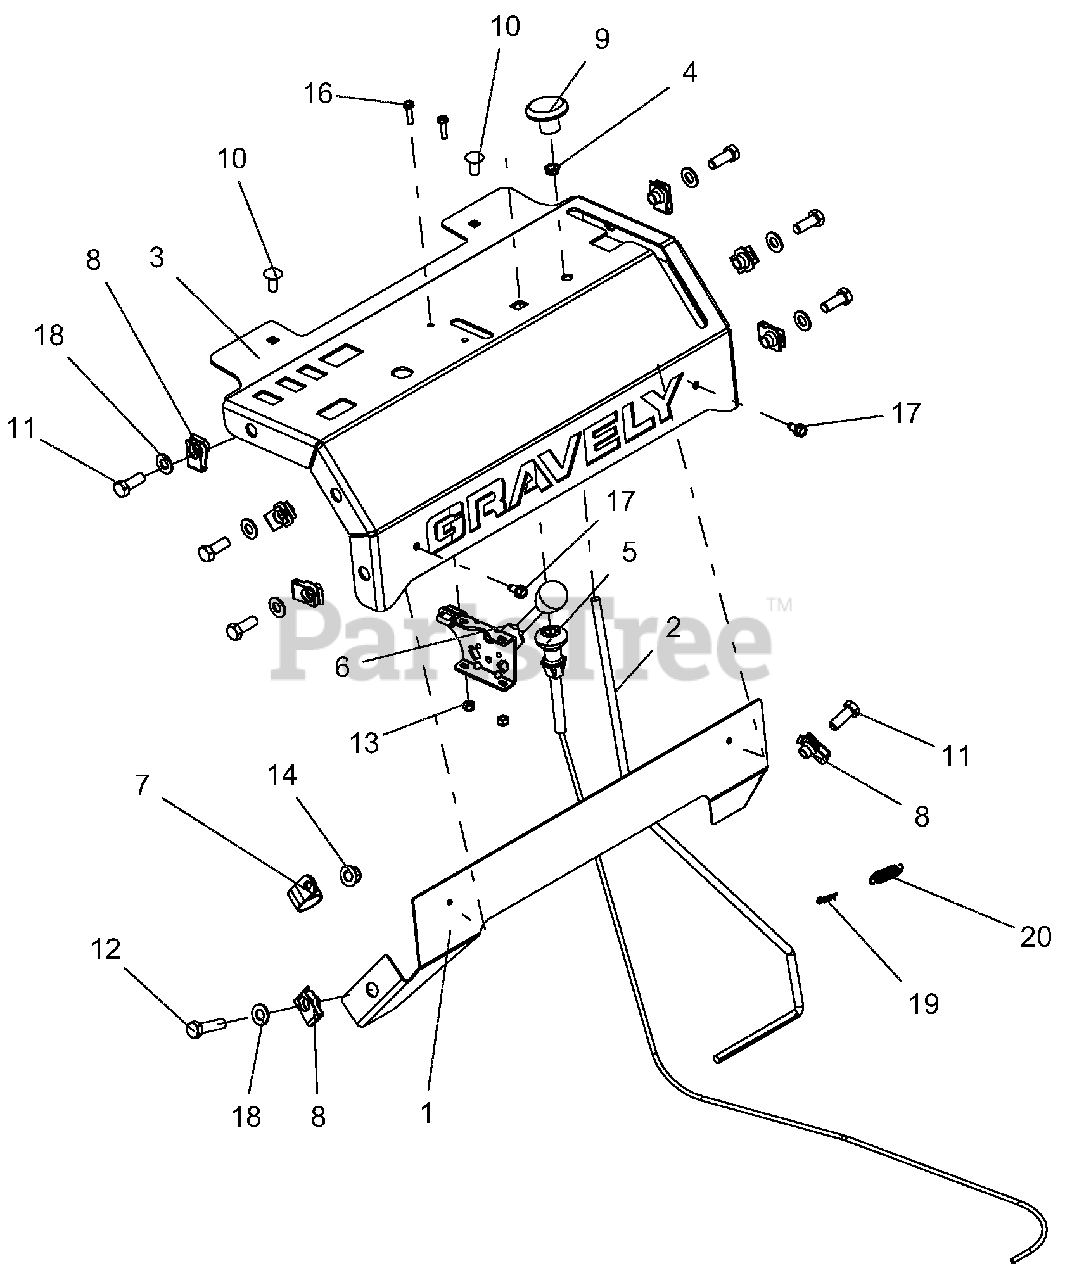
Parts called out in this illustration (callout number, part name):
1	PLATE, FRONT BACKER
2	WIREFORM, TRAILER LOCK
3	PANEL, CONTROL - PRO-STANCE
4	BSHG, POLYLINER-.38 SNAPIN
5	CABLE, CHOKE (SNAP IN)
6	CABLE, PRO-CONTROL THROTTLE
6	KNOB, CONTROL BLACK .38-16X.50
7	CLAMP, CUSHIONED STEEL REV
8	NUT, RTNR .375-16X.37
9	KNOB, PUSH -PULL .312-18
10	BLT-RDHDSQNK .31-18X.75 G5 YWZC
11	BLT-HEX .38-16X1.00 GR5 YWZC
12	BLT-HEX .38-16X1.50 GR5 YWZC
13	NUT-LK-NYL #10-24 YWZC
14	NUT-LK-NYL-FLG .38-16 YWZC
16	@SCR-MCH 10-24X.75 HWH YWZC
17	SCR-TAP .25-20X.50 HWH TR YWZ
18	WSHR-FL-STL.406X.812X.065 YWZ
19	PIN-HAIR, ENDRIES #25 YWZC
20	SPRG, EXTENSION
